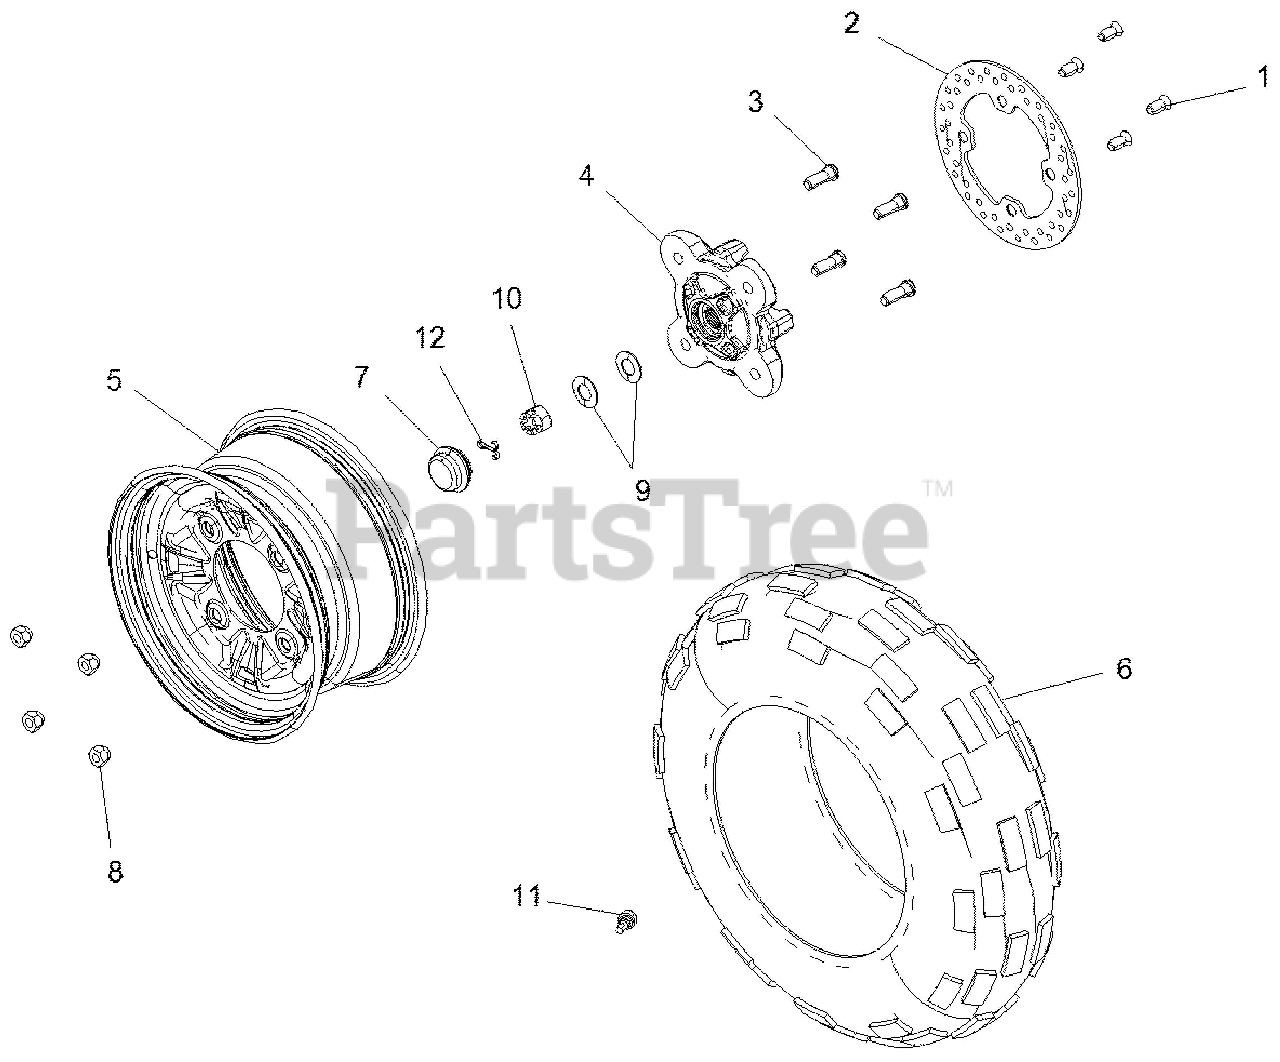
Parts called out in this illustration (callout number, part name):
1	SCR-M10X1.5X20 8.8 TXCS FL ZOD
2	DISC-BRAKE, FRONT
3	STUD-WHEEL,M12-1.5
4	HUB-WHEEL,FRONT(MACH),BLK
5	WELD-RIM,FR,10 GA,12X6,M.BLK
6	TIRE, FRONT, 25X10-12
7	HUB-DUST COVER,INTRNL LIP,BLNK
8	NUT-LUG,M12
9	WASHER, CONE
10	NUT-M18X1.5,CASTLE,ZINC/YELLOW
11	VALVE, RIM
12	PIN, COTTER
